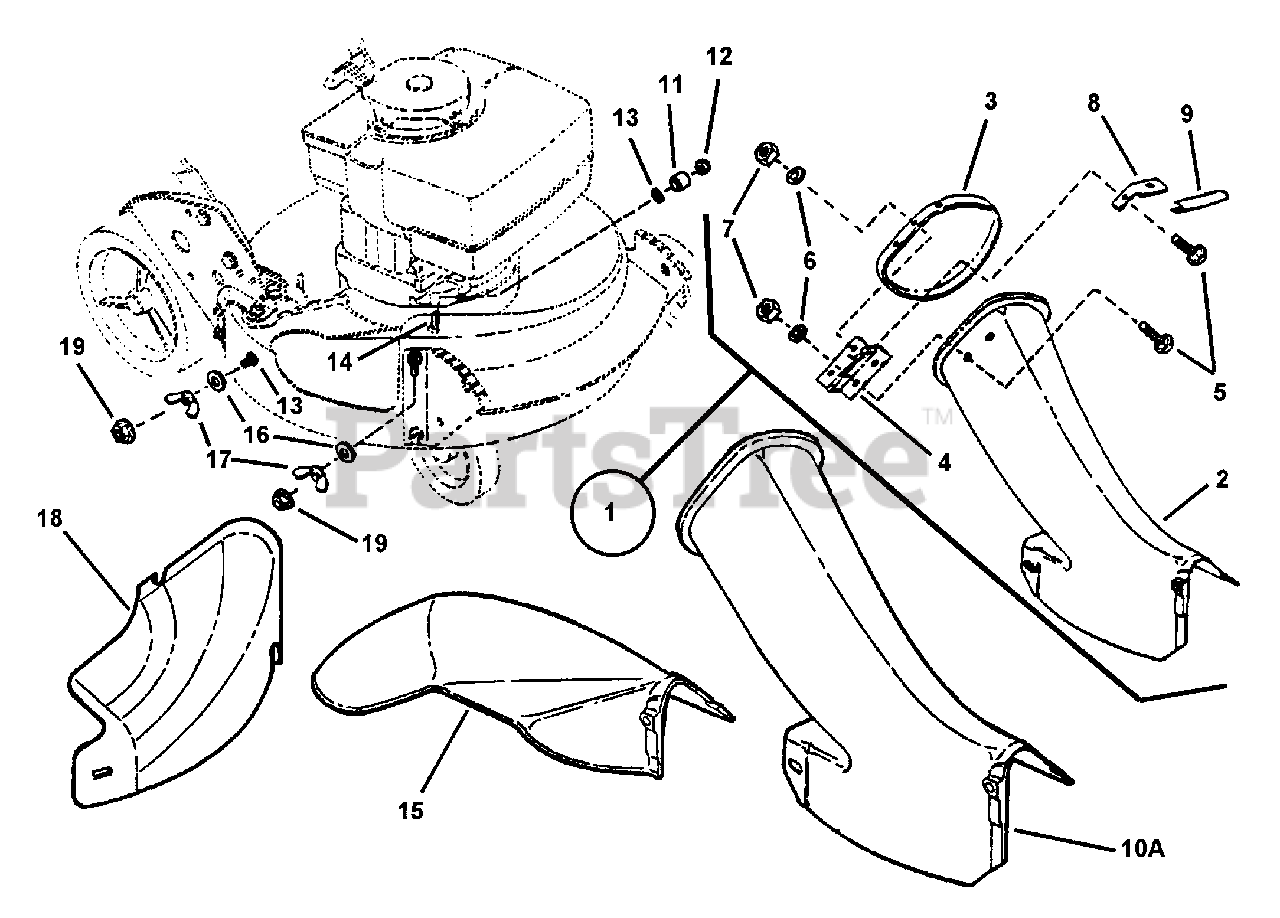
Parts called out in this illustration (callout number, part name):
1	ASSEMBLY, Bag Adapter & Cover
2	ADAPTER, Grass Bag
3	COVER, Bag Adapter
4	HINGE, Chute Cover
5	BOLT, 1/4-20 x 1/2" Short Neck Carriage, Grade 5
6	WASHER, 1/4 Internal Tooth Lock
7	NUT, 1/4-20 Hex, Grade 5
8	STOP, Cover
9	MOLDING, Trim
10A	ADAPTER, Grass Bag
10B	ASSEMBLY, Grass Bag Adapter
11	SPACER
12	NUT, 5/16-18 Hex Flange Center Lock
13	RETAINER, 5/16 Bolt
14	BOLT, 5/16-18 x 3/4" Short Neck Carriage, Grade 5
15	KIT, Side Chute
16	WASHER, 5/16 Flat
17	WING-NUT, 5/16-18 Nyloc
18	COVER, 21" Deck
19	NUT, 5/16-18 Large Flange Center Lock
